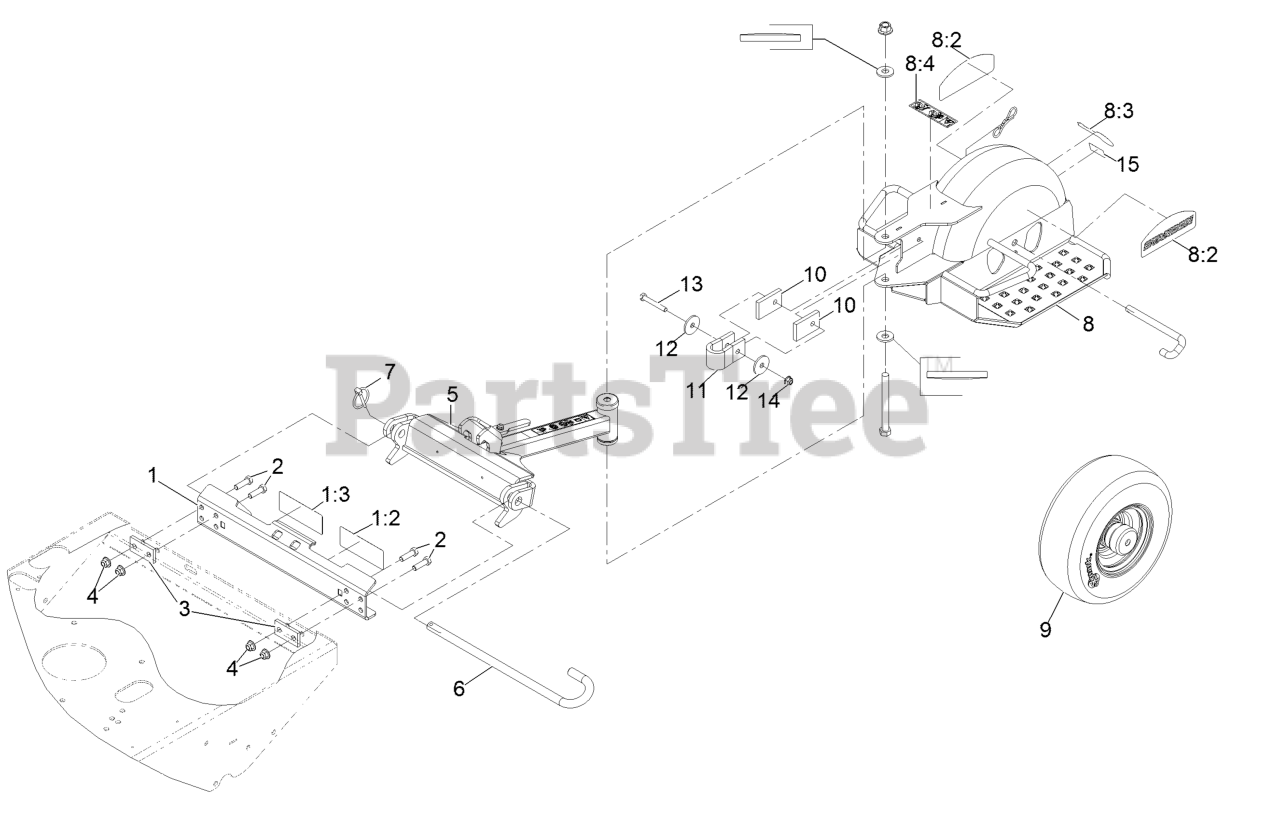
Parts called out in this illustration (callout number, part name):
1	ASM, Mount Plate
1:2	Decal-Belt Drive Warning
1:3	Decal-Warning, Sulky
2	Screw-HH 3/8-16 X 1 1/4
3	Plate, Back-Up
4	Nut-Nyloc 3/8-16 Flg
5	ASM, Draw Bar
6	Pin, Pivot
7	Pin-Lynch
8	ASM-Sulky Frame W/ Decals
8:2	Decal, Standon
8:3	Decal, Exmark
8:4	Decal-Warning Hand Pinch
9	ASM, Wheel And Bearings
10	Pad, Stop
11	Stop, Rotation
13	Screw-HH 5/16-18 X 2 1/4
14	Nut-Nyloc 5/16-18 Flg
15	Decal-Patent
